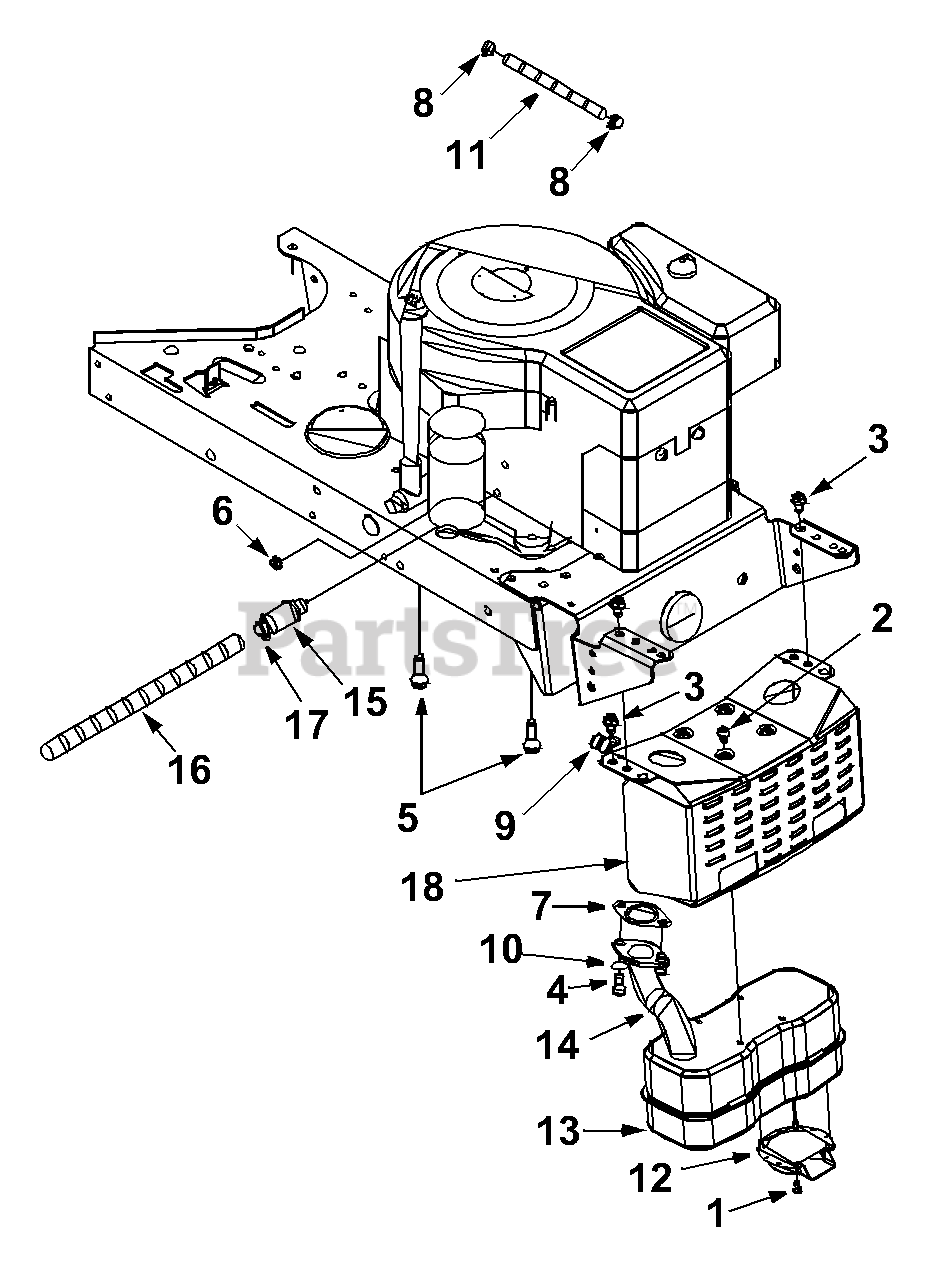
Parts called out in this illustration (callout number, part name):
1	Hex Bolt #8-32 x .38" Lg.
2	Hex Wash. Hd. TT-Scr. 1/4-20 x .5" Lg.
3	Hex Wash. Hd. TT-Scr. 5.16-18 x .62"
4	Socket Hd. Bolt 5.16-18 x .62" Lg.
5	Hex Wash. Hd. TT-Scr. 3.8-16 x 1.25"
6	Hex Sems Nut 1/4-20 Thd.
7	Exhaust Gasket
8	Hose Clamp
9	Clamp
10	Lock Washer 5/16" I.D.
11	Fuel Line Hose
12	Muffler Deflector
13	Muffler
14	Exhaust Pipe (16/17 HP)
15	OIl Drain
16	Oil Drain Hose Extension
17	Oil Drain Cap
